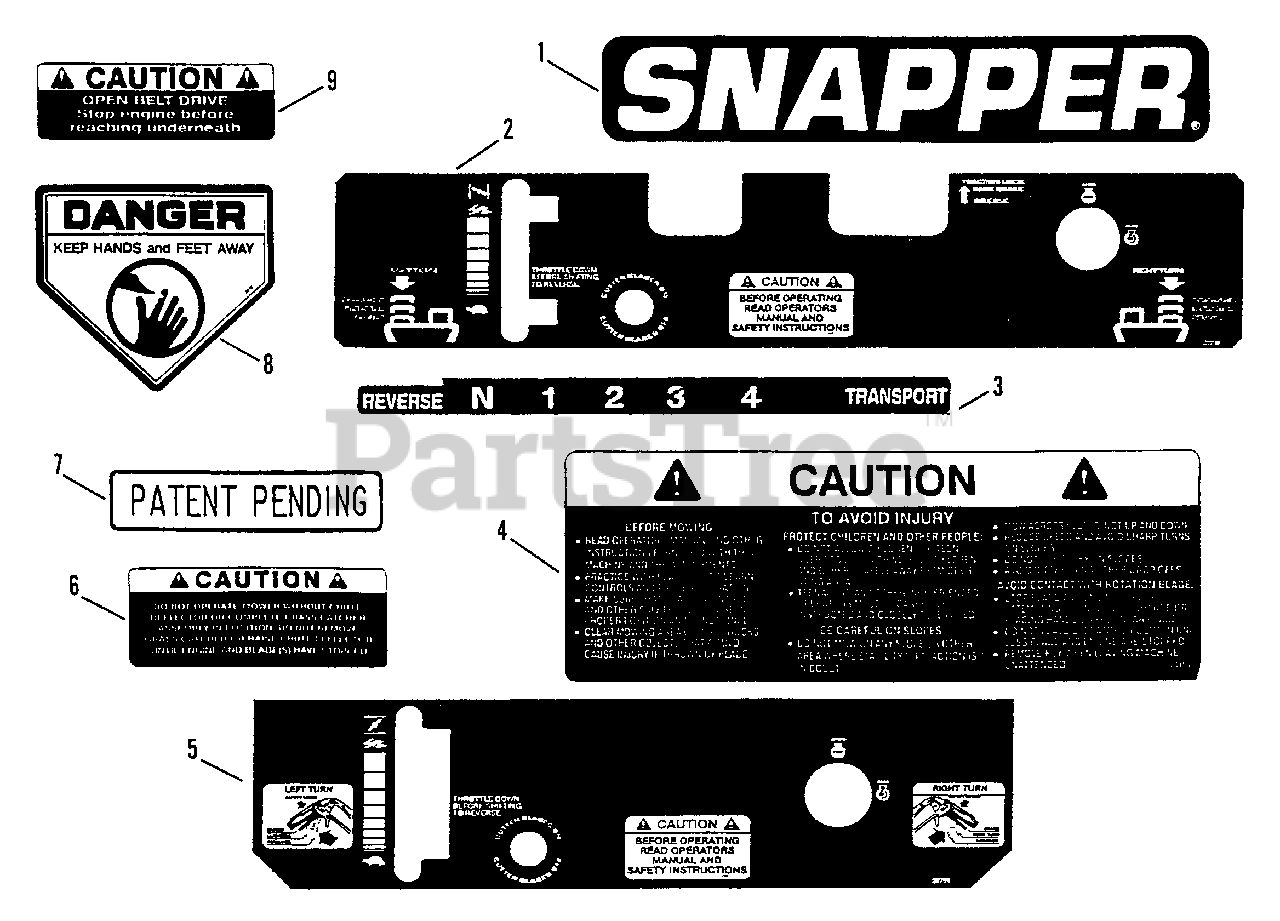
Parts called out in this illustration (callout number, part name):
1	DECAL, SNAPPER
2	DECAL, Console (Loop Handle)
3	DECAL, Shift Quadrant
4	DECAL, Caution
5	DECAL, Console (Pistol Grip Handle)
6	DECAL, Caution
7	DECAL, Patent Pending
8	DECAL, Warning
9	DECAL, Caution
